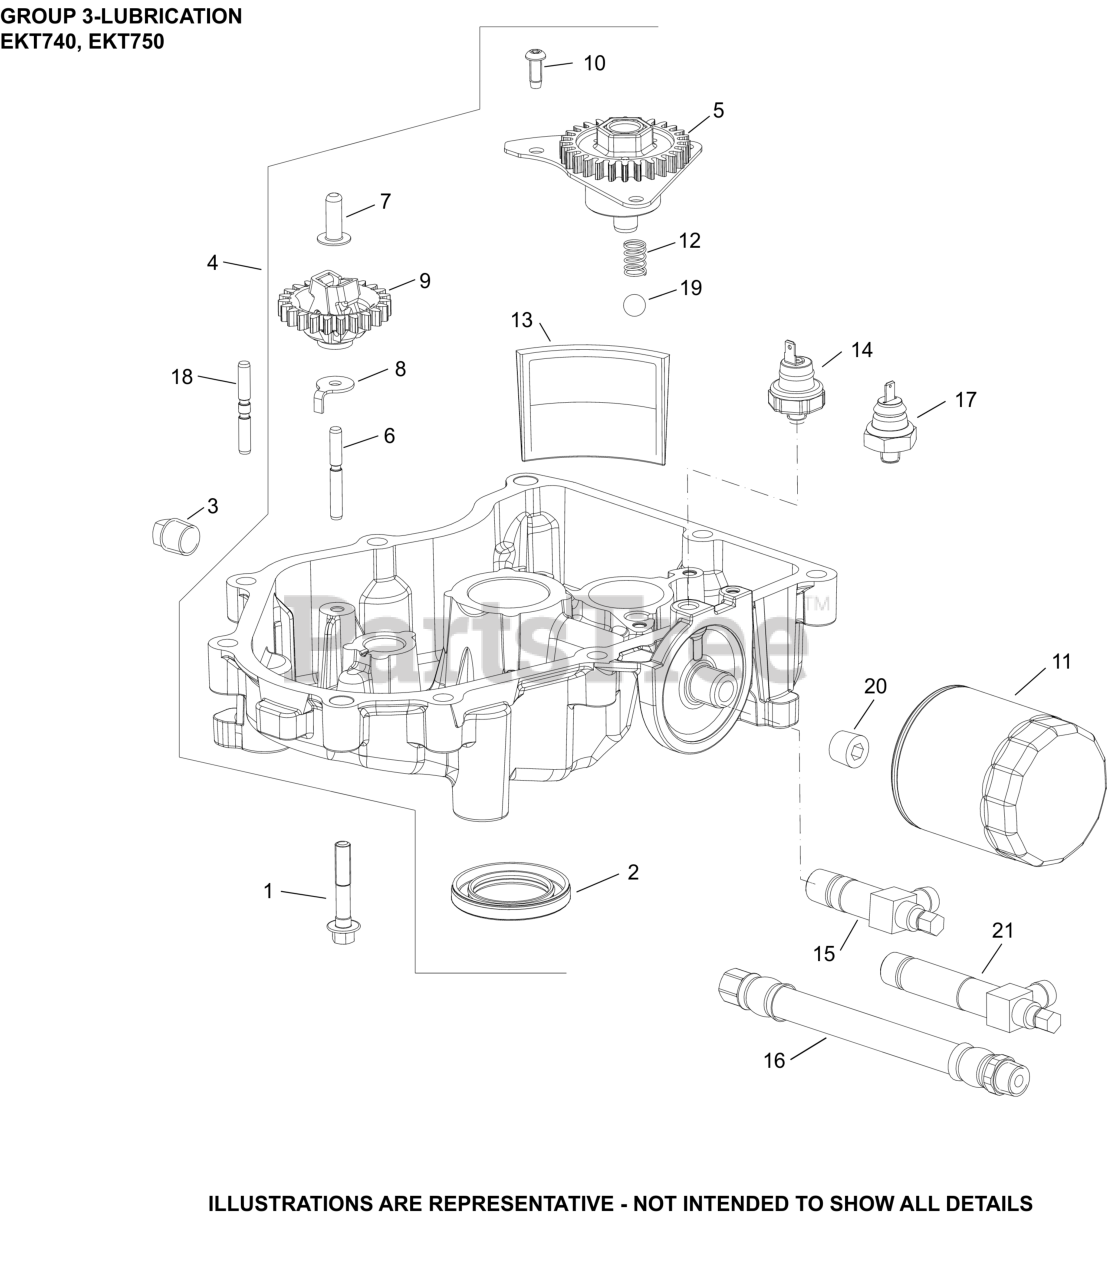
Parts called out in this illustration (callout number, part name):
1	SCREW, FLG M8X1.25X45
4	OIL PAN ASSEMBLY, (ROLLER BURNISHED)
5	PUMP ASSEMBLY, OIL
7	PIN, GOVERNOR REGULATING
8	TAB, LOCKING
9	KIT, GOVERNOR GEAR
10	SCREW, BUTTON HEAD
11	OIL FILTER
12	SPRING, COMPRESSION
13	SCREEN, OIL
17	SWITCH, OIL PRESSURE(NC 3-6 PSI TO OPEN)
18	SHAFT, GOVERNOR GEAR
19	PRESSURE RELIEF BALL
20	PLUG, PIPE CTSK 3/8"
21	VALVE, OIL DRAIN MEDIUM
